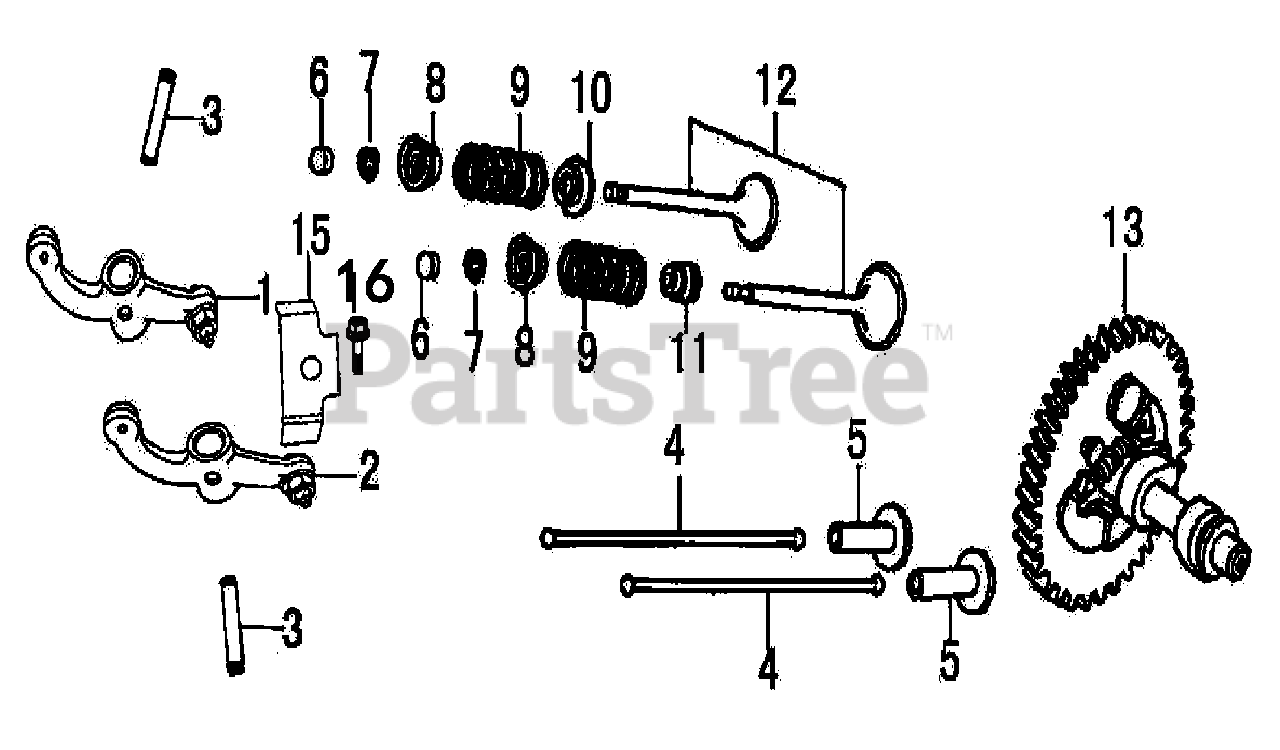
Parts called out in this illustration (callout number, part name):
1	ROCKER ARM ASSY.
2	ROCKER ARM ASSY.
3	VALVE ROCKER SHAFT
5	LIFTER, VALVE
6	ROTATOR, VALVE
7	KEEPER, VALVE
8	RETAINER, VALVE SPRING
9	SPRING, VALVE
10	SEAT, VALVE SPRING
11	SEAL, VALVE STEM
12	VALVE ASSY
13	CAMSHAFT ASSY
15	RETAINER, ROCKER ARM SHAFT
16	BOLT, FLANGE 6X12
